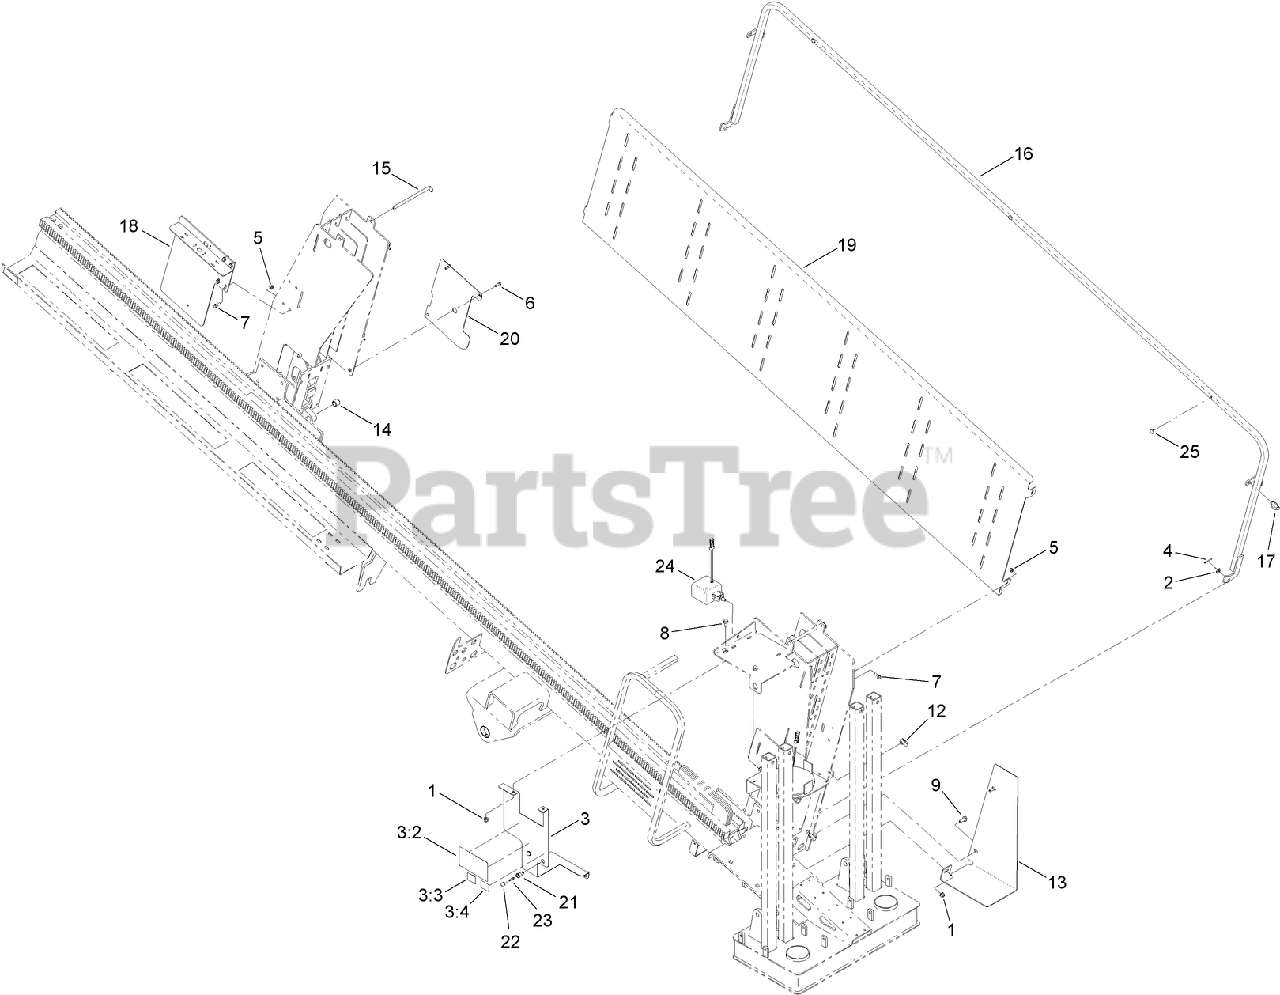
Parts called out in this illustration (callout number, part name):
1	NUT-LOCK, NI
2	WASHER-FLAT
3	GUARD PLATE ASM
3:2	DECAL-STAKEDOWN SET UP
3:3	DECAL-PIPE RETURN, CLEAR
3:4	DECAL-PIPE BREAKOUT, CLEAR
4	PIN-COTTER
5	NUT-LOCK, HHF
6	SCREW-HHF
7	SCREW-HHF
8	SCREW-HHF
9	SCREW-HHF
13	COVER-SIDE
14	BUSHING-SPRING
17	PIN-SNAP RING
18	PLATE-MOUNT, SWITCH
19	PANEL-ROD BOX
20	GUARD-ELEVATOR
21	TYPE T-2 SOCKET ASM
22	LENS-DOME, FLUTED GREEN (TYPE T2)
23	LAMP-LED
24	LIGHT-WORK
25	BUMPER
